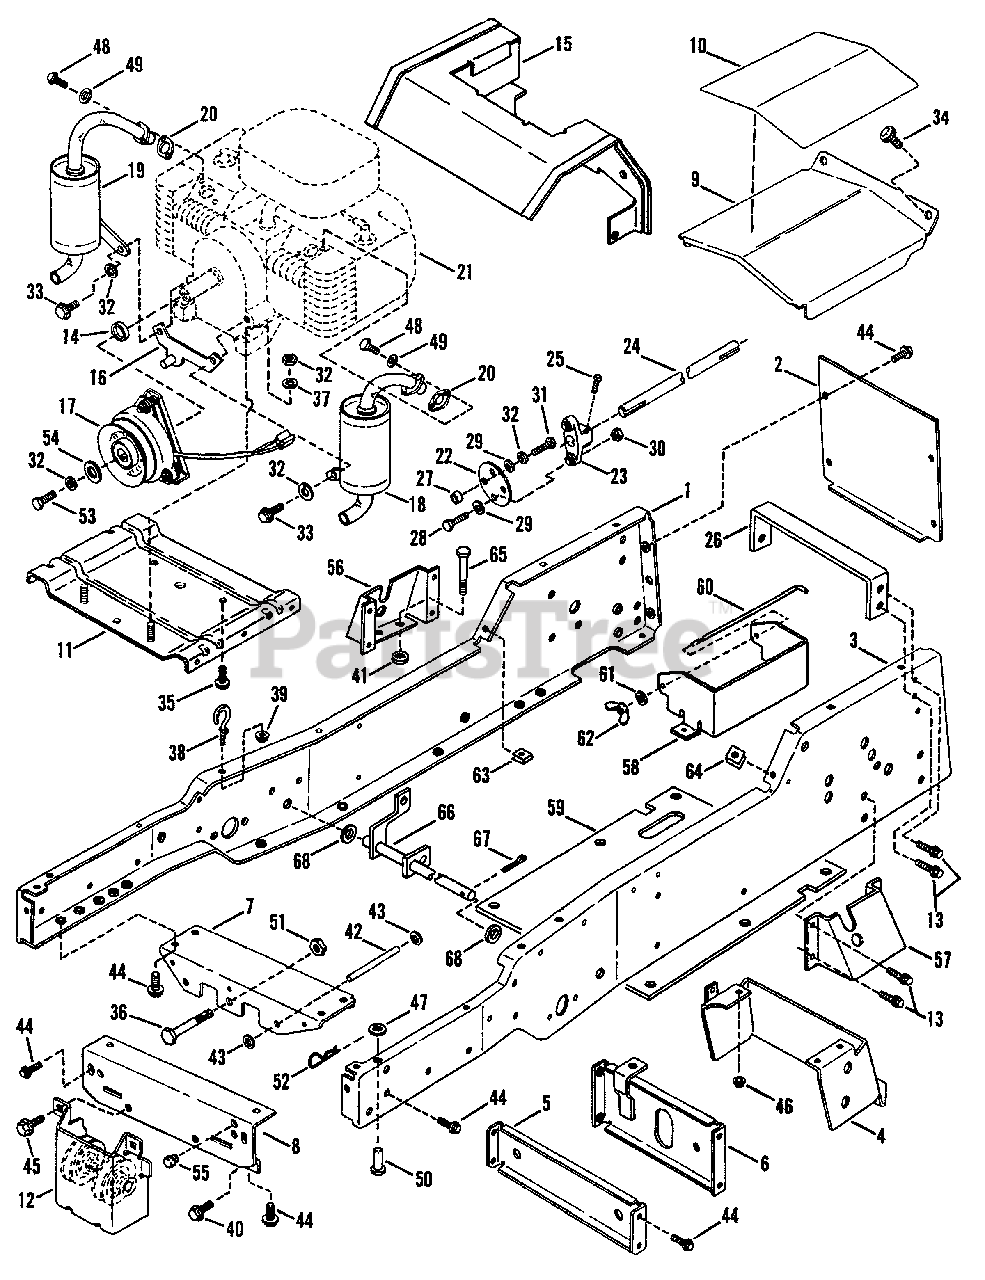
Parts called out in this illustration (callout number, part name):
1	CHANNEL, Right Hand Frame
2	PLATE, Rear Cover
3	CHANNEL, Left Hand Frame
4	DRAWBAR
5	BRACE, Forward
6	BRACE, Rear Cross
7	CHANNEL, Front Axle Support
8	PLATE, Front Frame
9	COVER, Console
10	DECAL, Console Cover
11	BASE, Engine
12	ASSEMBLY, Mule Drive
13	SCREW, 3/8-16 x 1/2" Hex Washer Self-Tap
14	SPACER, 1" x 1 3/8 x .30" (PM)
15	ASSEMBLY, Heat Shield
16	BRACKET, Clutch Retainer
17	KIT, Electric Clutch
18	MUFFLER, L.H.
19	MUFFLER, R.H.
20	GASKET, Exhaust
22	DISC, Flex Coupling
23	HUB, Flex Coupling
24	SHAFT, Drive
25	SET-SCREW, 5/16-18 x 1/2" Square Head
26	STRAP, Cross
27	SPACER, Flexible Coupling
28	SCREW, 3/8-16 x 1", Hex Head Cap, Grade 2
29	WASHER, 3/8" Flat
30	NUT, 3/8-16 Hex Center Lock, Grade B or 5
31	SCREW, 3/8-16 x 1-1/4" Hex Head Cap, Grade 5
32	WASHER, 3/8 Split Lock
33	SCREW, 3/8-16 x 7/8", Hex Head Cap, Grade 5
35	SCREW, 7/16-14 x 3/4" Self-Tapping
36	SCREW, 1/2-20 x 4" Hex Head Cap, Grade 5
37	NUT, 3/8-16 Hex
38	HOOK, Hood Latch
39	NUT, 5/16-18 Hex Flange, Grade 5
40	SCREW, 1/4-20 x 5/8" Hex Washer Self-Tap
41	RETAINER, 3/8 Bolt
42	STOP, Axle
43	RETAINER, 3/8 Shaft
44	SCREW, 5/16-18 x 5/8" Hex Washer Self-Tap
45	BOLT, 3/8-16 x 3/4" Hex Flange Lock
46	NUT, 3/8-16 Hex Flange Lock
47	PUSH-NUT, 1/2
48	SCREW, 5/16-18 x 7/8" Socket Head Cap
49	WASHER, 5/16 Split Lock
50	PIN, 1/4 x 7/8" Clevis
51	NUT, 1/2-20 Hex Nyloc
52	PIN, 1/4 Hair
53	SCREW, 3/8-24 x 1-1/2" Hex Head Cap, Grade 5
54	WASHER, .406 I.D.
55	RELIEF, Strain
56	SUPPORT, R.H. axle
57	SUPPORT, L.H. Axle
58	BRACKET, Battery
59	STIFFNER, Frame
60	CLAMP, Battery
61	WASHER, 1/4" SAE
62	WING-NUT, 1/4-20
63	U-NUT, 1/4-20
64	CLIP
65	SCREW, 3/8-24 x 3-3/4" HHC
66	SHAFT & LEVER
67	COTTER-PIN, 3/32 x 3/4"
68	WASHER, 3/8 SAE
